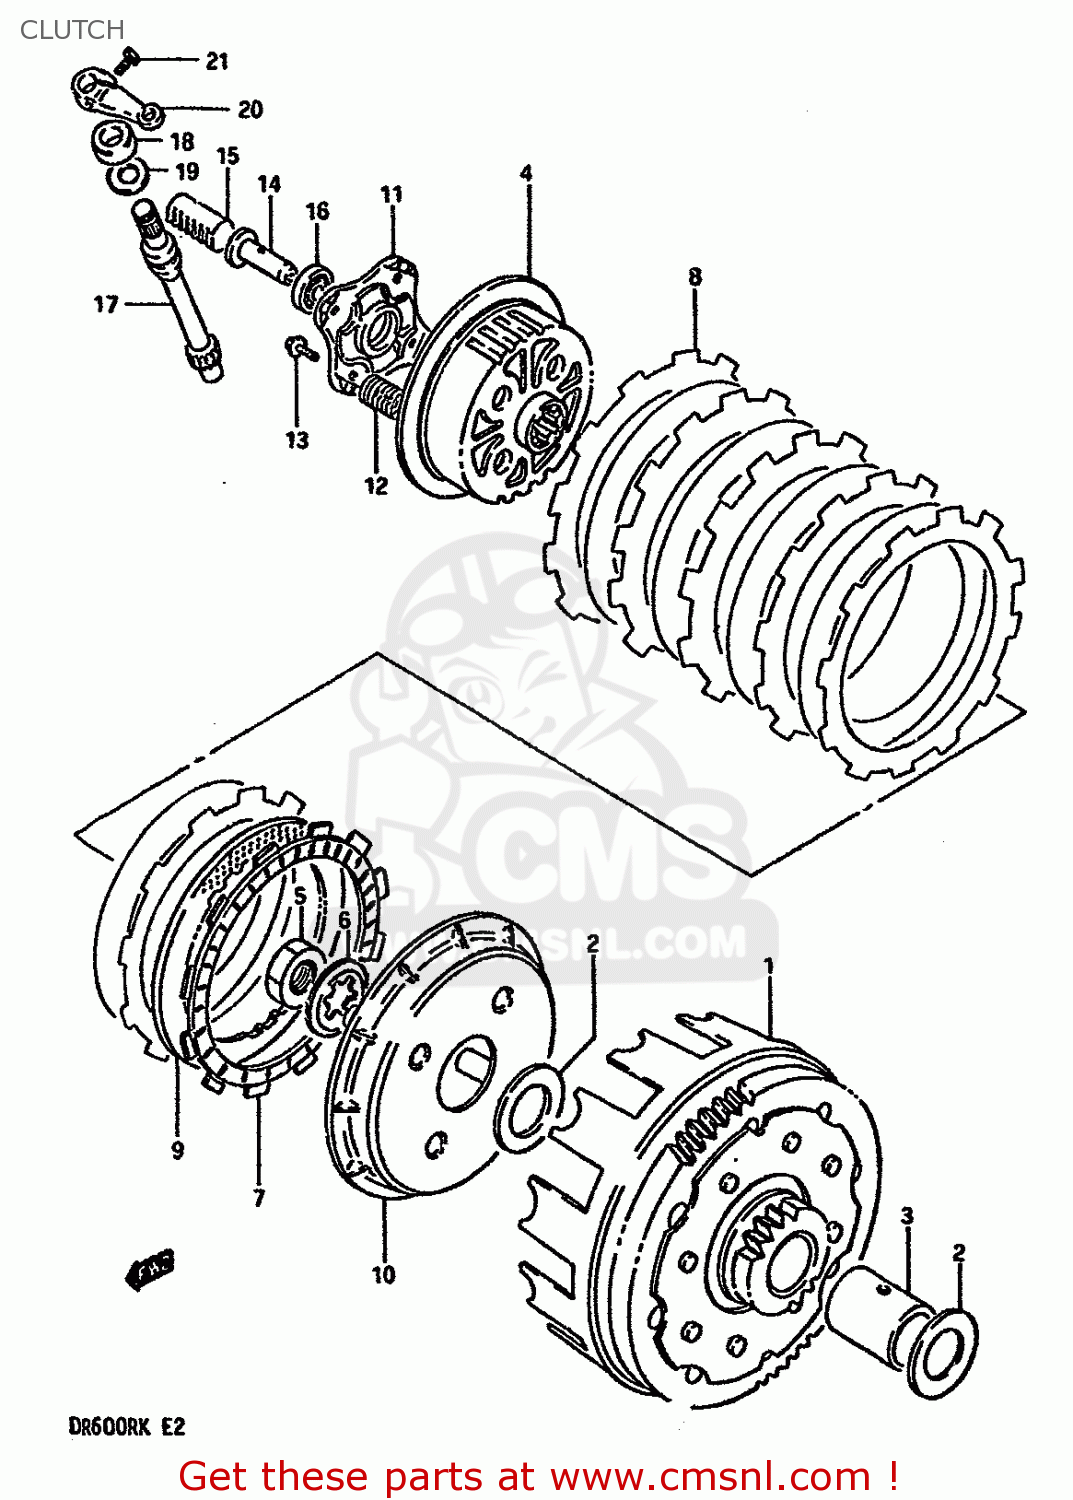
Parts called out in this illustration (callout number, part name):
1	GEAR ASSEMBLY,PRIMARY DRIVE
2	WASHER
3	SPACER(22X28X32.5)
4	HUB,CLUTCH SLEEVE
5	NUT
6	WASHER,LOCK
7	PLATE,CLUTCH DRIVE (NAS)
8	PLATE,CLUTCH DRIVE(T:3.5) (NAS)
9	PLATE,CLUTCH DRIVEN(T:1.6) (NAS)
10	DISC,CLUTCH PRESSURE
11	PLATE,RELEASE
12	SPRING
13	BOLT 6X20
14	PIECE,CLUTCH PUSH
15	RACK,CLUTCH RELEASE
16	BEARING
17	PINION,CLUTCH RELEASE
18	SEAL,OIL (12X22X9)
19	WASHER (14.2X22X1)
20	ARM,CLUTCH RELEASE
21	BOLT
